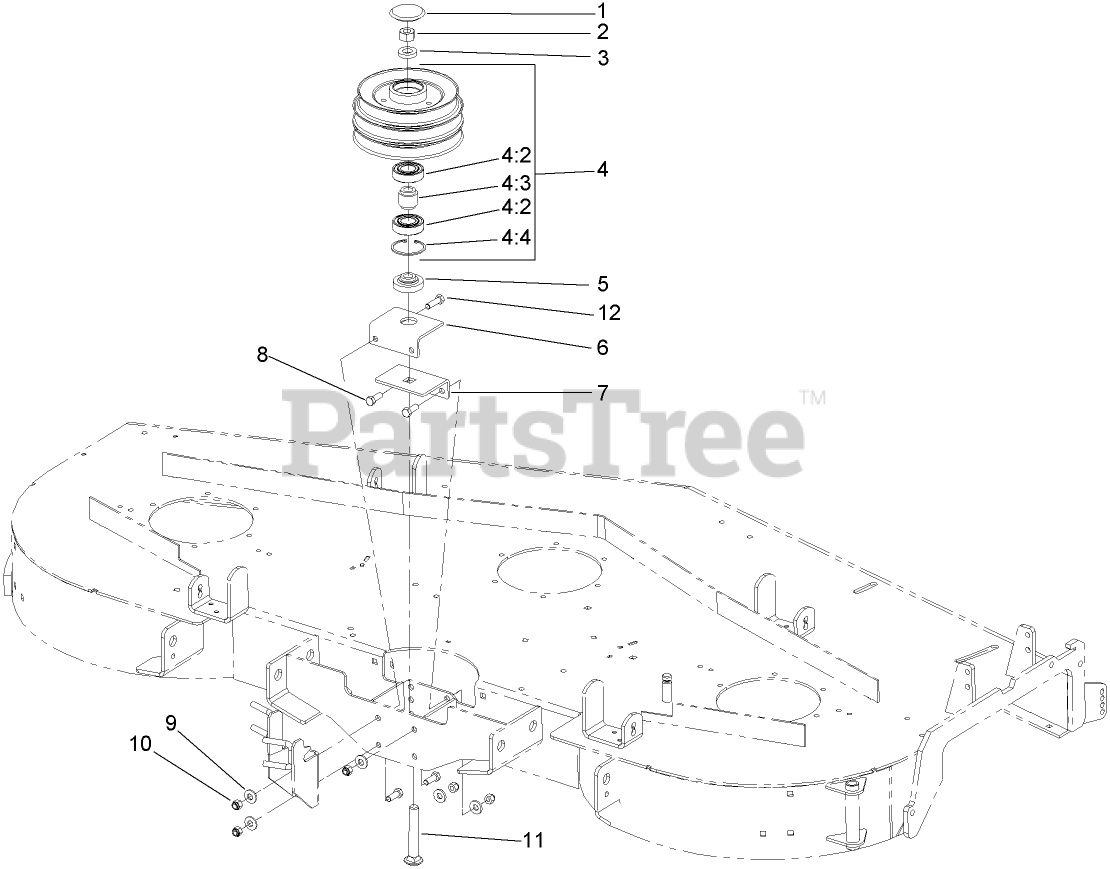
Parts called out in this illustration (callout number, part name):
1	CAP-PLASTIC
2	NUT-HEX
3	SPACER
4	PULLEY AND BEARING ASM
4:3	SPACER-BEARING
4:4	RING-SNAP
5	SPACER-FLANGED
6	BRACKET-TOP
7	BRACKET-BOTTOM
8	SCREW-HH
9	WASHER-BELLEVILLE
10	NUT-LOCK, NI
11	BOLT-CARRIAGE
12	SCREW-HH
